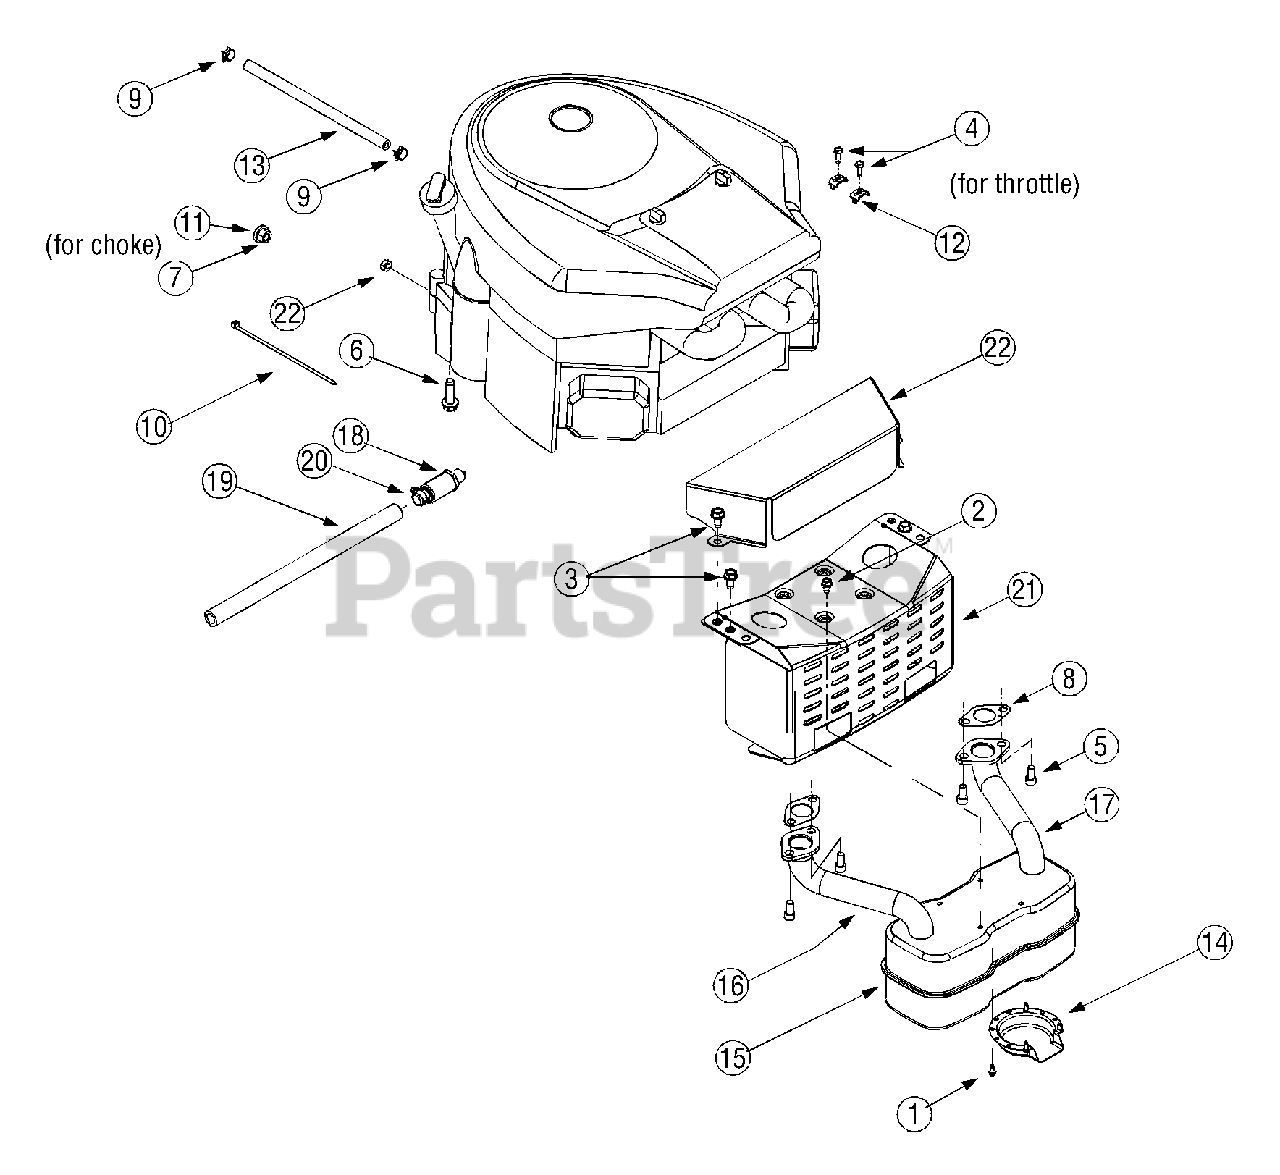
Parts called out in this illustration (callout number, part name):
1	Screw, #8-18 x .50
2	Screw, 1/4-20 x .50
3	Screw, 5/16-18 x .750
4	Screw, #10-32 x .625
5	Socket Cap Screw, 5/16-18 x .625
6	Self-tapping Screw, 3/8-16 x 1.25
7	Hex Flange Lock Nut, 3/8-16
8	Exhaust Gasket
9	Hose Clamp
10	Cable Tie
11	Lock Washer, .406 x .875 x .059
12	Casing Clamp
13	Fuel Line Hose
14	Muffler Deflector
15	Muffler, Twin Inlet
16	RH Exhaust Pipe
17	LH Exhaust Pipe
18	Oil Drain Valve
19	Oil Drain Hose
20	Oil Drain Cap
22	Sems Nut, 1/4-20
